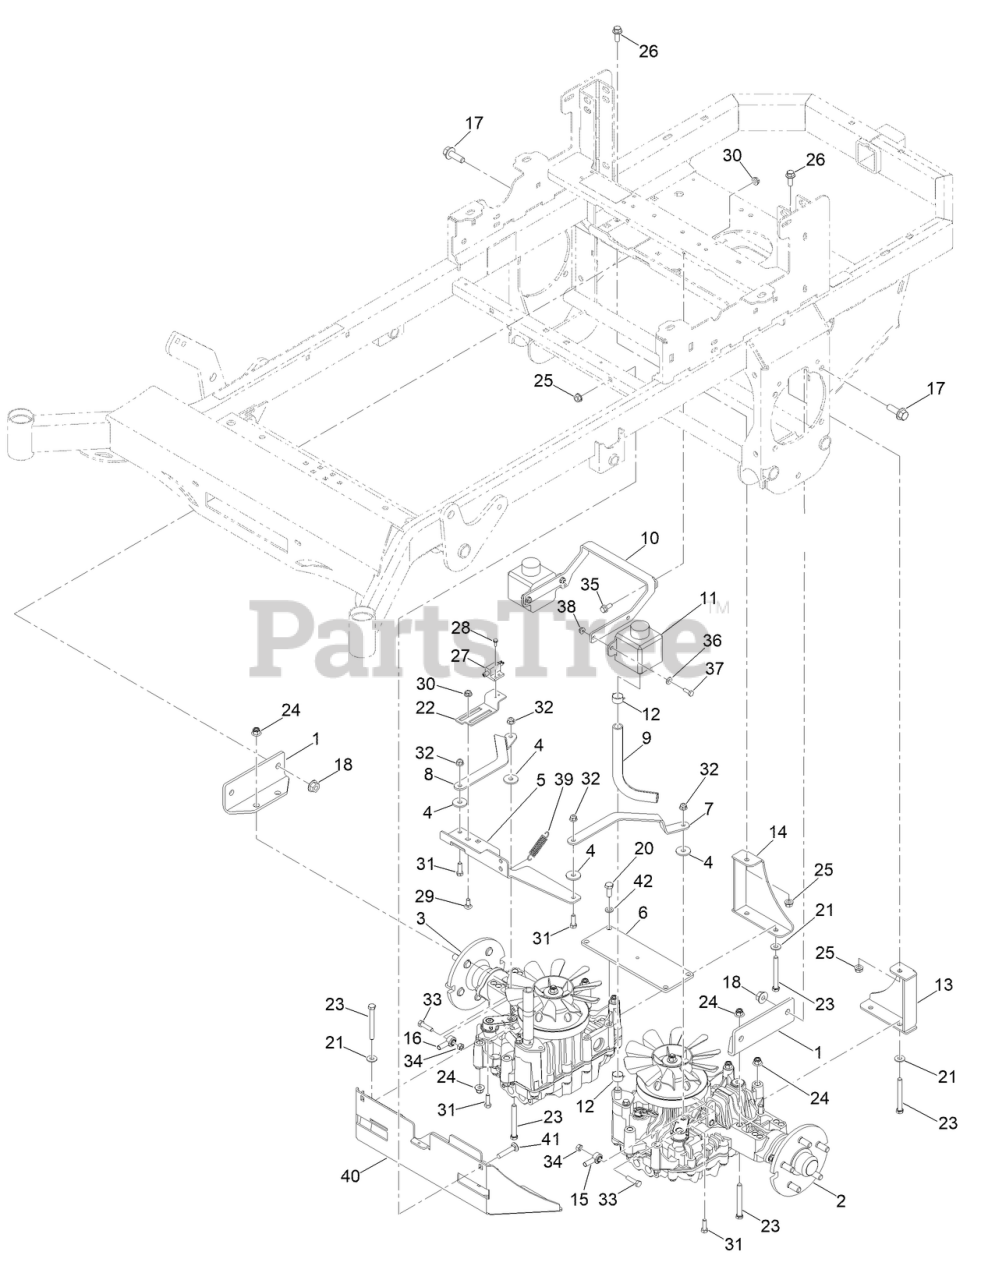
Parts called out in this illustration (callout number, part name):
1	TT13 DRIVE MOTOR MOUNTING BRACKET
2	2023 TZT-13 LT SIDE HYDRO TRANSMISSION
3	2023 TZT-13 RT SIDE HYDRO TRANSMN
4	FLT WASHER 1.25ODX.38IDX.125 THK PLA
5	TT13 BRAKE ROD BRACKET
6	TT13 TRANSMISSION MOUNT BRACE
7	TT13 BRAKE ROD PLATE LEFT SIDE
8	TT13 BRAKE ROD PLATE RIGHT SIDE
9	MWR 5/8IN HYDRAULIC HOSE, 1FT
10	BRACKET-RESERVOIR
11	RT-PRO TT13 1/4 LITER HYDR FLUID RESRV
12	22MM HOSE CLAMP (CTB-22ST-FK)
13	TT13 DRIVE MOTOR MOUNTING REAR LEFT BRKT
14	TT13 DRIVE MOTOR MOUNTING REAR RIGHT BRK
15	5/16-24 SPHER ROD END ZINC LH THD FEM
16	5/16-24 SPHER ROD END ZINC RH THD FEM
17	SCREW-HHF
18	NUT-HHF
20	M10 X 1.5 X 25MM TAP BOLT
21	WASHER-FLAT
22	TT13 BRAKE INTERLOCK BRACKET: PAINTED
23	3/8IN-16X3-1/4IN HEX HD CAP SCR
24	3/8-16 NYLOCK FLANGE NUT
25	3/8-16 HEX FLANGE NUT W/SERR ZINC YELLOW
26	SCREW-HHF
27	NO PLUNGER LIMIT SWITCH
28	8-32 X 1/2 IND. HWH SLOT TYPE F TCS ZINC
29	BOLT-CARR
31	SCREW-HH
32	NUT-HF, NI
33	SCREW-HH
34	5/16-24 NYL INS L/N GR.8 ZC/YEL
35	SCREW-HHF
36	1/4 FLAT WASHER BLACK 18-8 BLACK ZINC
37	SCREW-HH
38	NUT-HF
39	MWR BRAKE PEDAL RELEASE SPRING
40	TT13 BATTERY BOX MOUNT PLATE PAINTED
41	SCREW-CARR
42	WASHER-LOCK
